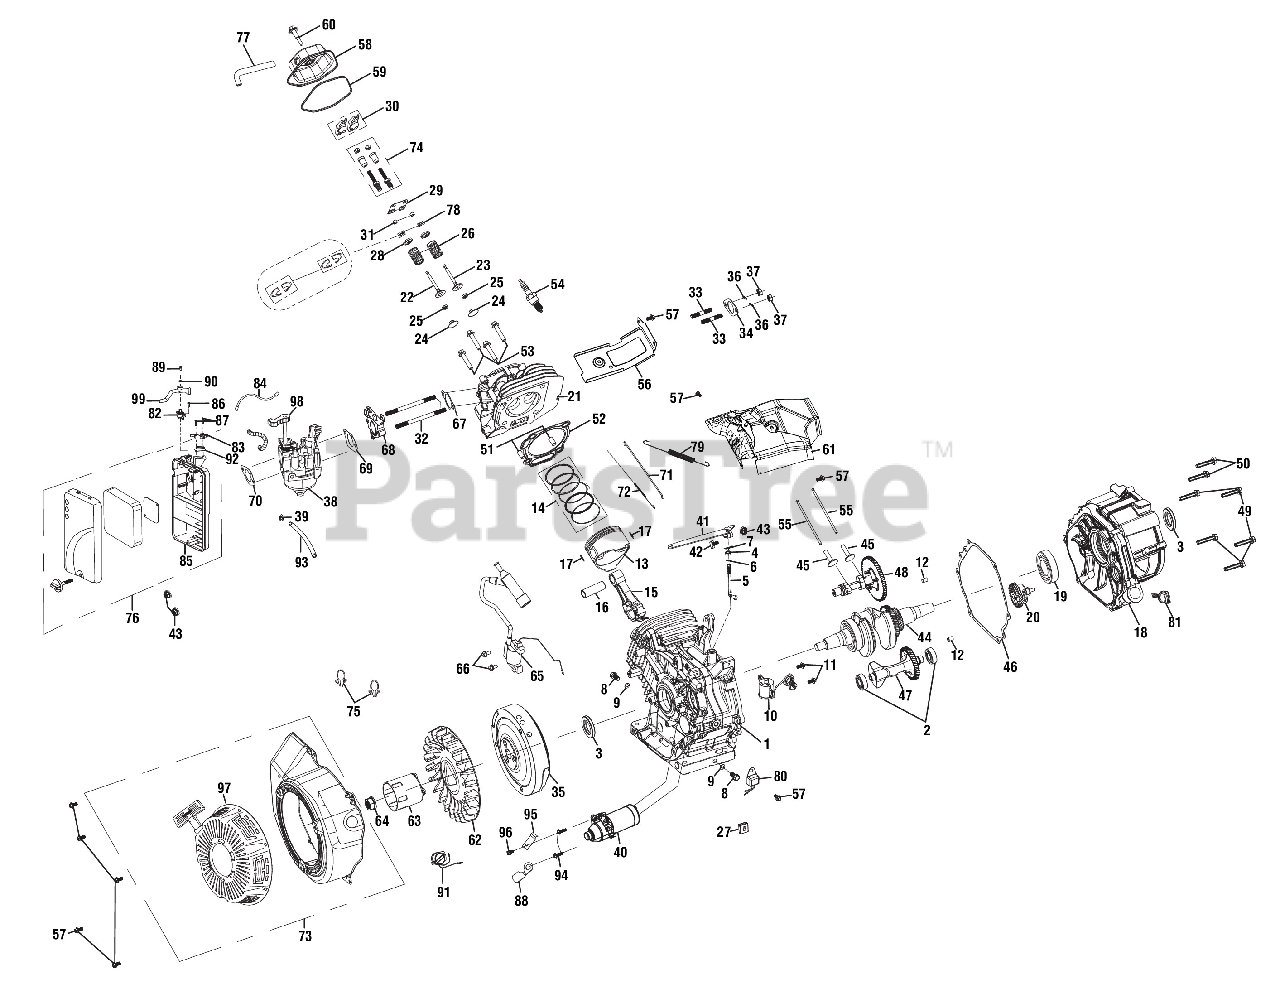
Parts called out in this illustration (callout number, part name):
1	Crankcase
2	Ball Bearing
3	Oil Seal
4	Governor Arm Shaft Seal
5	Governor Arm Shaft
6	Governor Arm Shaft Washer
7	Lock Pin
8	Drain Plug Bolt.
9	Drain Plug Washer
10	Oil Level Switch Assembly
11	Bolt (M6 x 16 mm)
12	Casecover Dowel Pin
14	Piston Scraper Ring Set
15	Connecting Rod Assembly
16	Piston Pin
17	Piston Clip
18	Crankcase Cover Assembly
19	Ball Bearing
20	Governor Assembly
21	Cylinder Head
22	Intake Valve
23	Exhaust Valve
24	Intake Valve Returner
25	Oil Seal Valve
26	Valve Spring
27	Starter Assembly Rubber
28	Exhaust Valve Spring Seat
29	Push Rod Guide Plate
30	Rocker Assembly
32	Stud Bolt
33	Stud Bolt
34	Exhaust Packing
35	Flywheel Assembly
36	Spring Washer
37	Hex Nut (M8)
38	Carburetor Assembly
39	Fuel Hose Clamp (9.5 mm)
40	Starting Motor Assembly
41	Governor Arm
42	Governor Arm Bolt
43	Hex Nut (M6)
44	Crankshaft Assembly
45	Valve Lifter
46	Casecover Package
47	Balancing Shaft
48	Camshaft Assembly
49	Bolt (M8 x 35 mm)
50	Bolt (M8 x 40 mm)
51	Dowel Pin
52	Cylinder Head Gasket
53	Bolt (M10 x 80 mm)
54	Spark Pulg
55	Push Rod.
57	Bolt (M6 x 12 mm)
58	Cylinder Head Cover Comp
59	Headcover Packing
60	Lock Bolt
61	Upper Shroud Assembly
62	Recoil Starter Fan
63	Starter Pulley
64	Hex Nut (M5)
65	Ignition Coil Assembly
66	Bolt (M6 x 25 mm)
67	Intake Packing
68	Carburetor Insulator
69	Carburetor Packing
70	Carburetor Spacer
71	Governor Rod
72	Throttle Return Spring
73	Recoil Starter Assembly
74	Rocker Arm Adujuster
76	Air Cleaner Assembly
77	Breather Tube
78	Locking Flaps
79	Governor Spring
80	Amplifier
81	Dipstick
82	Fuel Valve
83	Enginge Stop Switch
84	Flameout Wire
85	Air Cleaner Bottom Cover
86	Screw (M6 x 10 mm, Pan Hd.)
87	Screw (St 2.9 x 16 mm, Pan Hd)
88	Clamper Cord A
89	Screw (M4 x 10 mm, Phillips Pan Hd.)
90	Washer (ID4.3 x OD10 x 0.9t)
91	Switch Assembly
92	Engine Switch Bracket
93	Fuel Hose (300 mm)
94	Bolt (M6 x 28 mm)
95	Clamper Cord A
96	Bolt (M6 x 8 mm)
97	Recoil cover
98	Choke Lever (Grey)
99	Control Lever (Grey)
